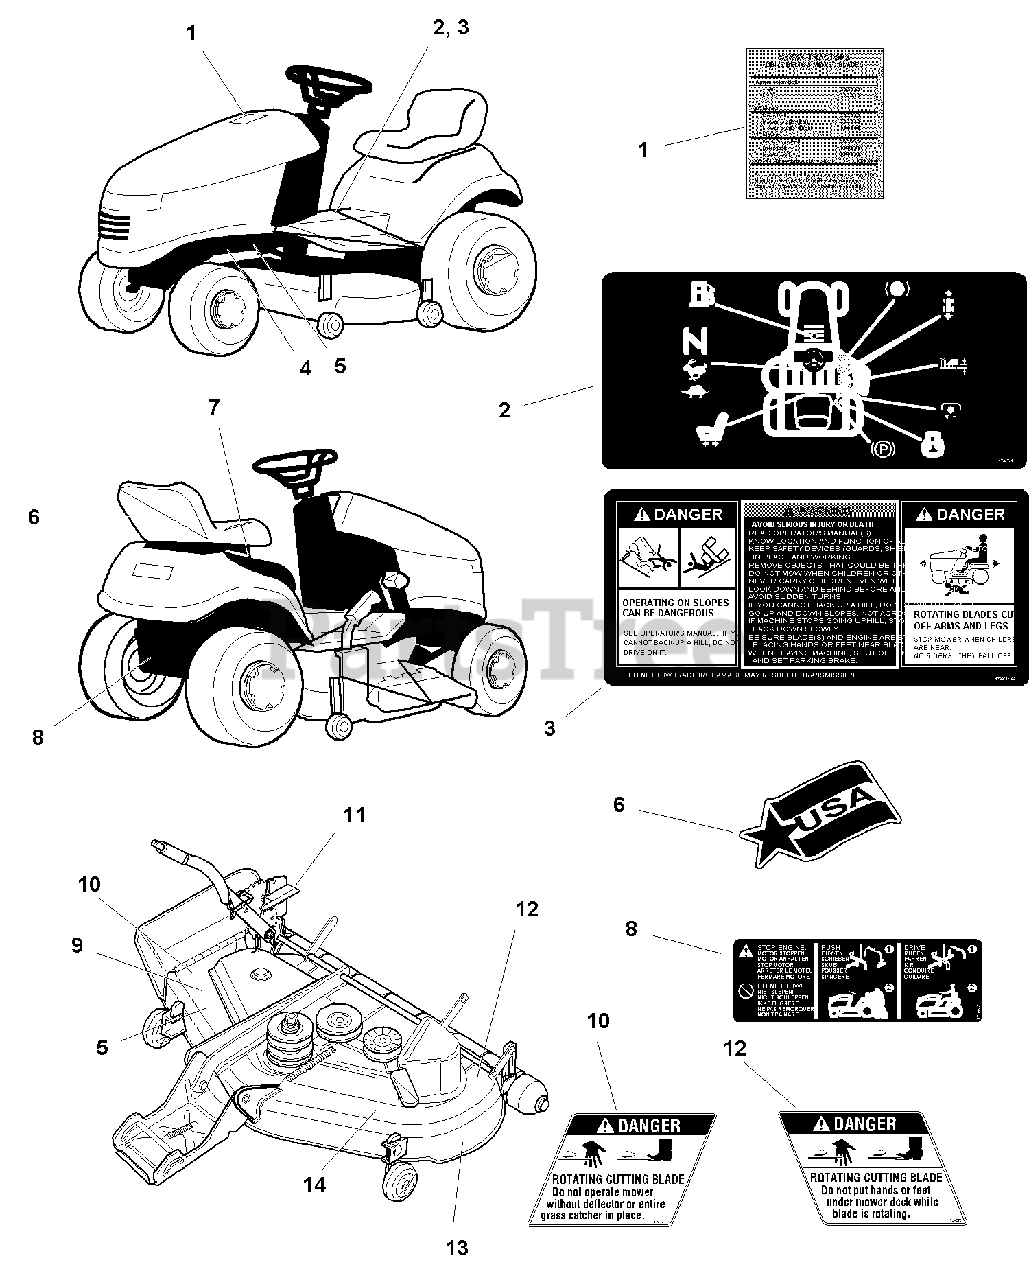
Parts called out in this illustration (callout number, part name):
1	DECAL, Belts & Mower Blades
2	DECAL, Control Locations
3	DECAL, Safety Instructions
4	DECAL, Patent (Not Serviced)
5	DECAL, Serial Number (Not Serviced)
5	DECAL, CE & Serial Number Export (Not Serviced)
6	DECAL, USA Logo
7	DECAL, PTO Control Symbols
8	DECAL, Transmission Release Valve, Hydros Only
10	DECAL, Danger, Rotating Blades
11	DECAL, Height of Cut
12	DECAL, Danger, Rotating Blades
13	DECAL, Free Floating Mower
14	DECAL, OPEI (Not Serviced)
